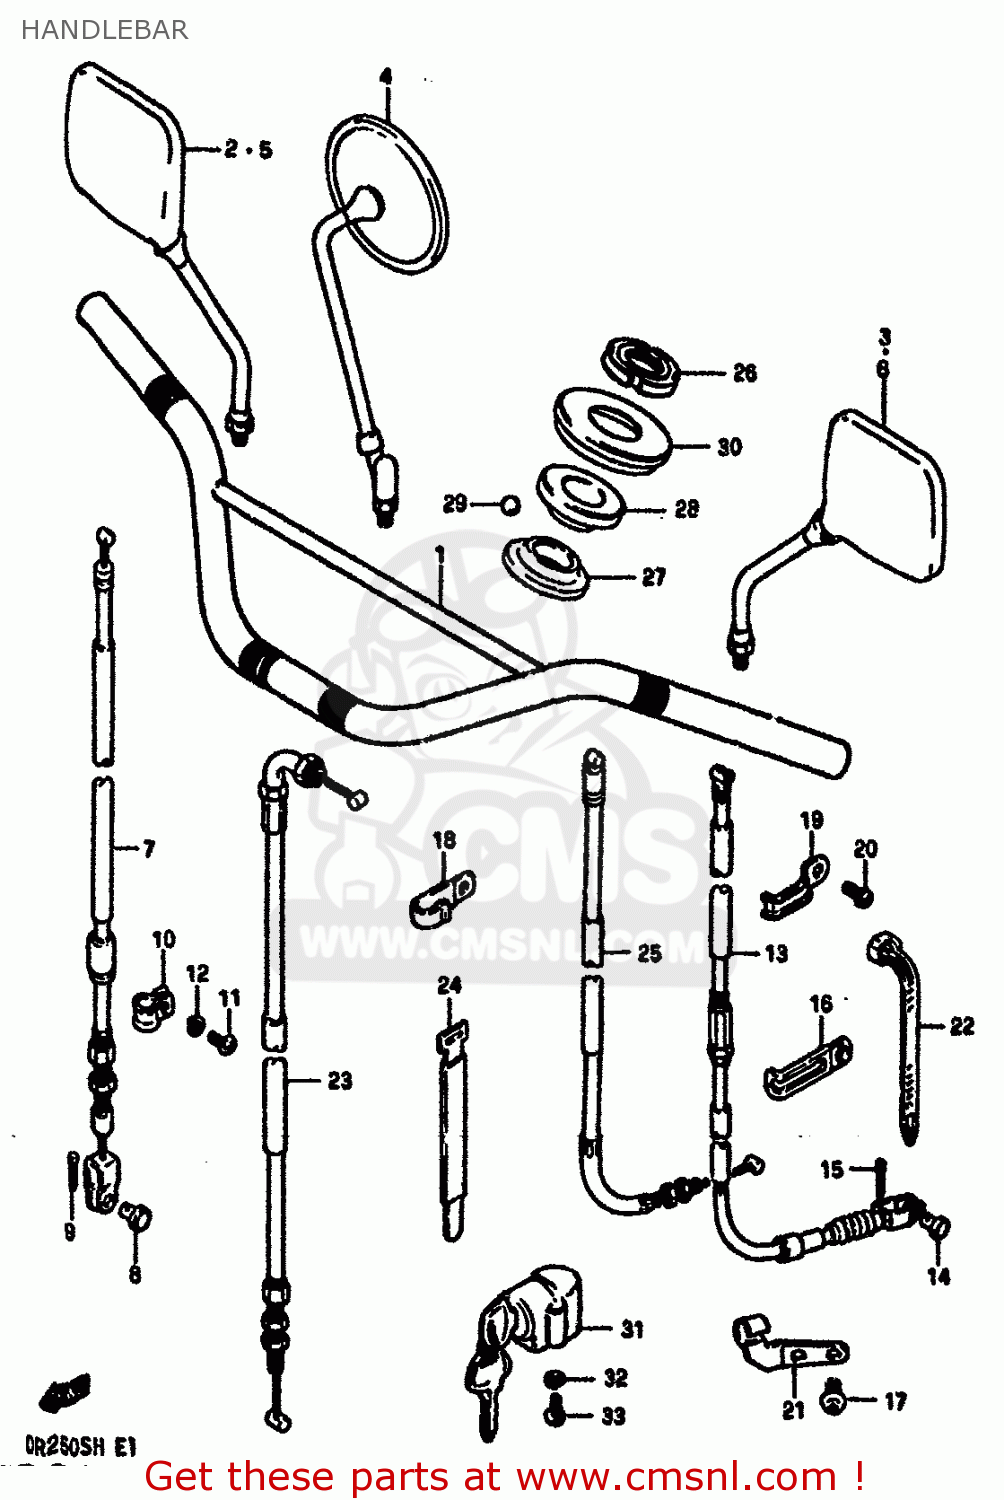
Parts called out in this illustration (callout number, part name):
1	HANDLEBAR
2	MIRROR ASSEMBLY,REAR VIEW
3	MIRROR ASSEMBLY,LEFT
4	MIRROR ASSY,RH
5	MIRROR, REAR VIEW RH
6	MIRROR, REAR VIEW LH
7	CABLE ASSY,FR BRAKE
8	PIN(L:17.5)
9	PIN
10	CLAMP,FR BRAKE CABLE
11	SCREW
12	WASHER,LOCK
13	CABLE ASSEMBLY,CLUTCH
14	PIN(L:13)
15	PIN
16	CLAMP
17	SCREW
18	CLAMP
19	CLAMP
20	SCREW
21	STTOPPER,CLUTCH CABLE
22	CLAMP(L:165)
23	CABLE ASSY,THROTTLE NO.1
24	CLAMP(L:250)
25	CABLE ASSEMBLY,DECOMPRESSION
26	NUT,STEERING STEM
27	RACE,STEERING INNER (SUJ)
28	BALL
30	SEAL,STEERING UPR DUST
31	LOCK ASSY,STEERING
32	LOCK WASHER
33	SCREW
